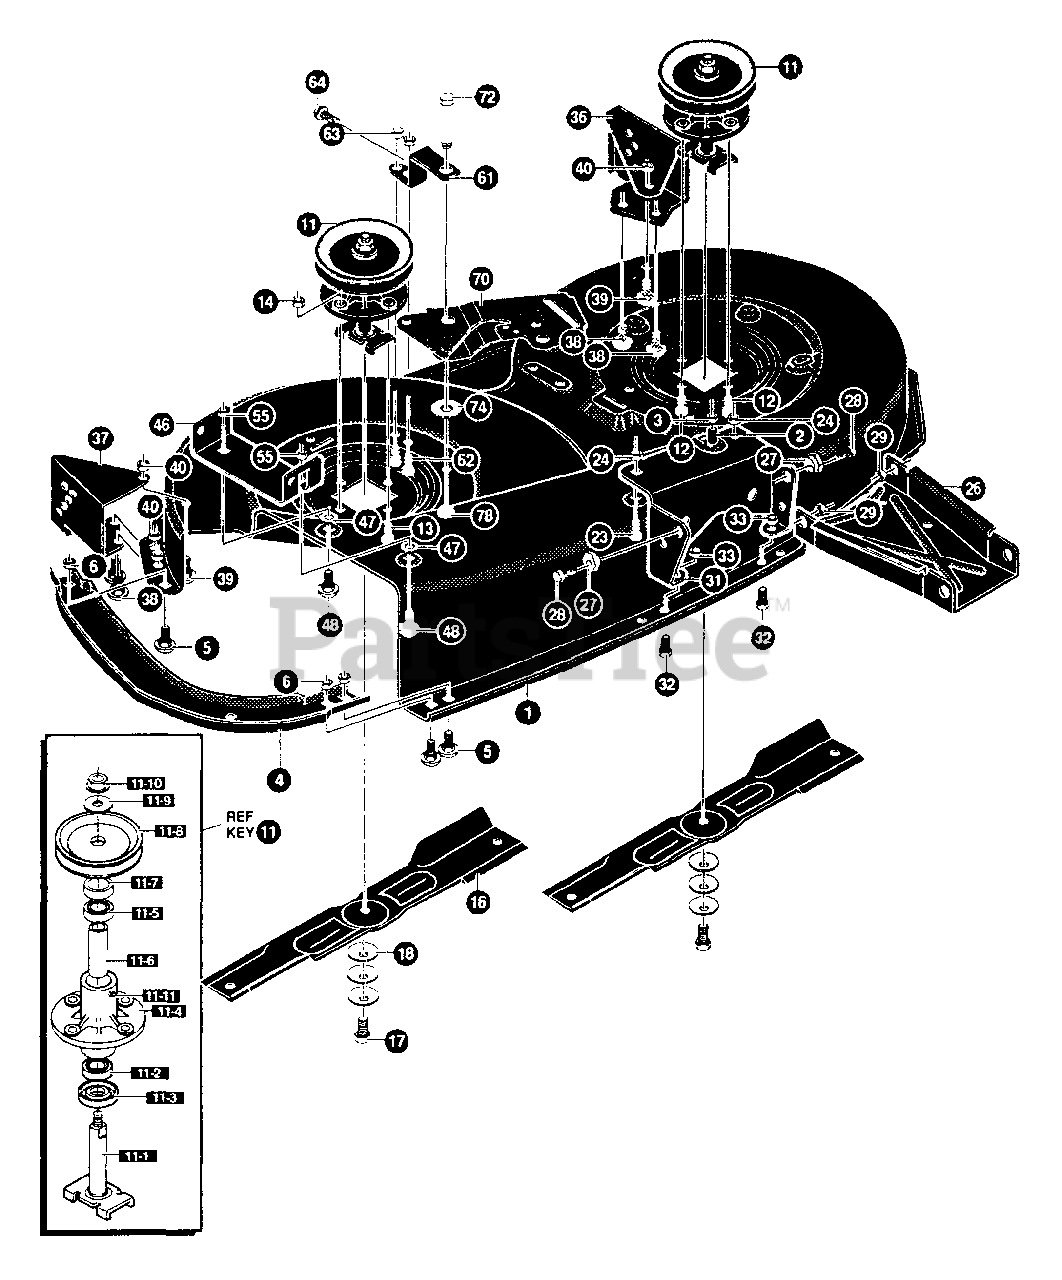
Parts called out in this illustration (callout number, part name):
1	MOWER DECK KIT 40" LF/EURO
2	SCREW, 5/16-18X.75 HHC
3	NUT, 5/16-18 REGHEXCTRLK
4	TOE GUARD - MULCHER
5	BOLT 5/16-18X.63 CARRLN
6	NUT, 5/16-18 REGHEXCTRLK
11	QUILL 36/40/43 W/ZERKS
12	SCREW, 5/16-18X.75 WAHHTAP
13	SCREW, 5/16-18X1.38 WAHHTAP
14	NUT, 5/16-18 REGHEXCTRLK
16	BLADE, 40" STD-LIFT 20.32
17	SCREW, 3/8-24X1.00 NYLHHC
18	WASHER, .39IDX1.25DX.07 BELLVIL
23	BOLT, 5/16-18X.63 CARRLN
24	NUT, 5/16-18 REGHEXCTRLK
26	CHANNEL DRAWBAR 40 EURO
27	NUT, ADJUST
28	SCREW 5/16-18X1.00 HHC
29	NUT, 5/16-18 REGHEXCTRLK
31	BRACKET FRONT
32	SCREW, 5/16-18X.75 HHC
33	NUT, 5/16-18 REGHEXCTRLK
36	BRACKET, GAGE WHEEL LH
37	BRACKET, GUAGE WHEEL RH
38	SCREW, 5/16-18X.75 HHC
39	BOLT, 5/16-18X.63 CARRLN
40	NUT, 5/16-18 REGHEXCTRLK
46	BRACKET CHUTE MOUNT
47	WASHER, FLAT .469X.92X.065
48	BOLT, 5.16-18X.63 CARR
55	NUT, 5/16-18 REGHEXCTRLK
61	BRACE IDLER SUPPORT 40",43"
62	SCREW, 5/16-18X.75 HHC
63	NUT, 5/16-18 HWDFLCTRLK
64	SCREW, 1/4-20X1.25 HHWATAP
70	IDLER ARM40/43/46DECK
72	BOLT, 500X2.15 HHSH
74	WASHER, FLAT .391X1.00X .209
78	NUT, 3/8-16 HWDFLLK MACK
